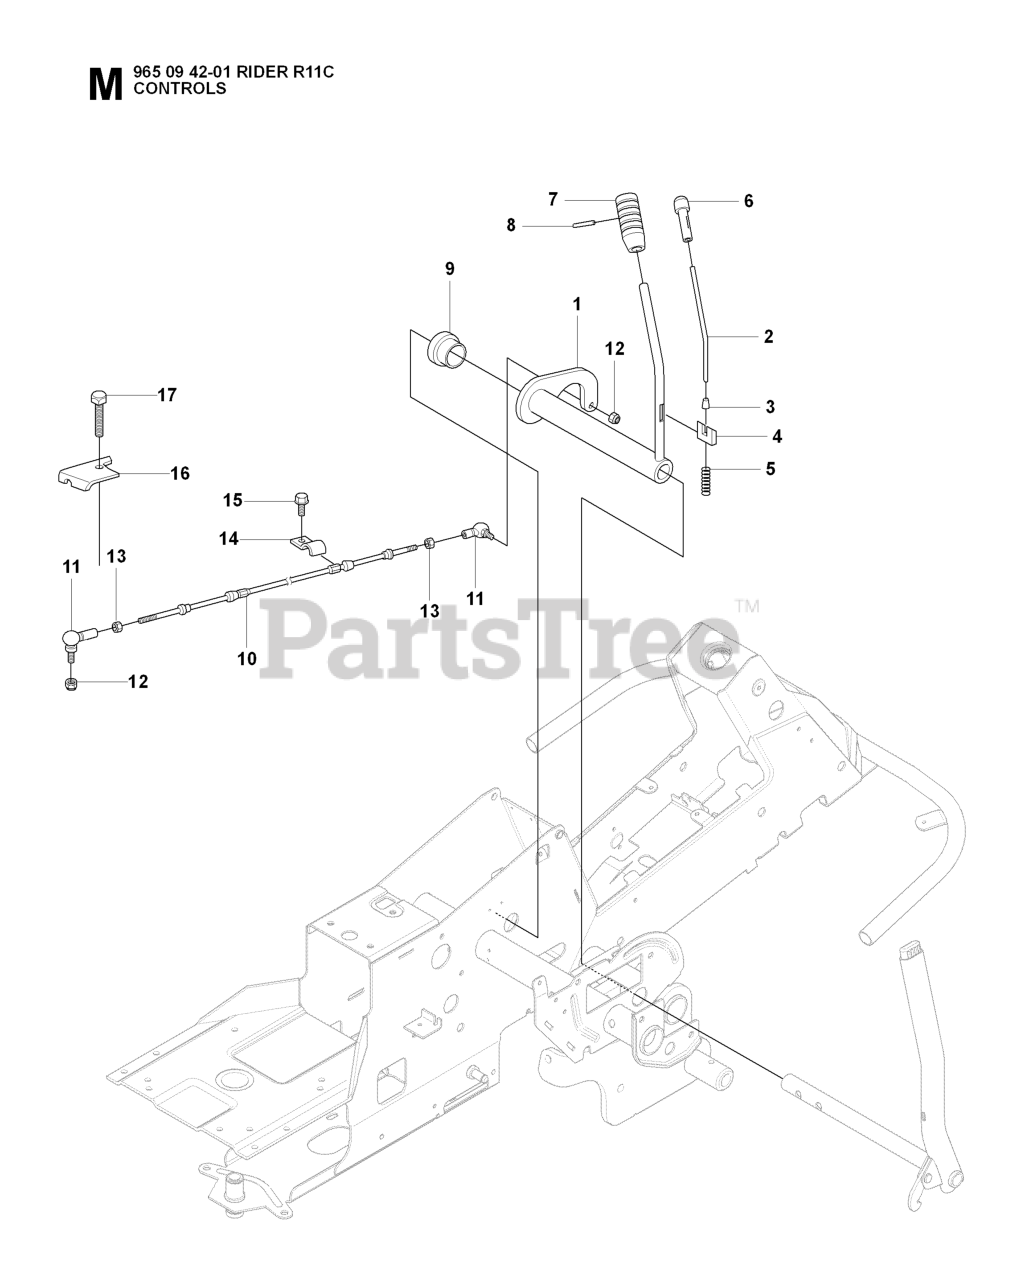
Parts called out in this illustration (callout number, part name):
8	SPRING PIN 3X24
9	BEARING FLANGE
10	%ROD
11	CONNECTOR
12	LOCKNUT M5
